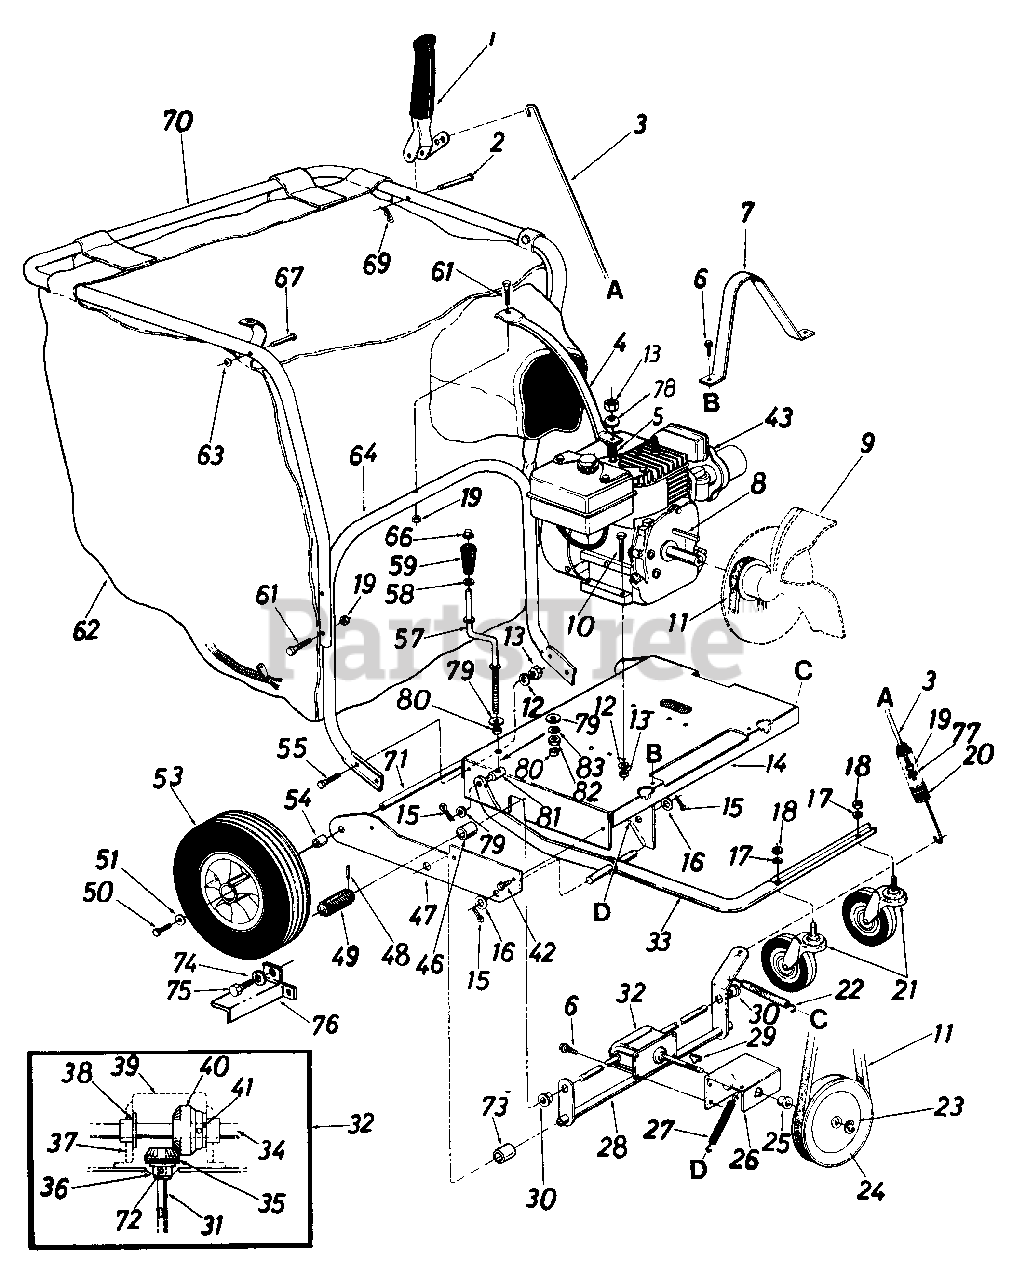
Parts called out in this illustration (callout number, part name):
1	Clutch Grip Ass'y.
2	Clevis Pin .375" Dia. x 1.88"
3	Clutch Rod 32" Lg.
4	Handle Brace
5	Part of Engine
6	Hex Wash. Hd. AB-Tap Scr. 1/4" x .62" Lg.
9	Air Vane Plate Ass'y. w/Pulley
10	Hex Bolt 5/16-18 x 1.5" Lg.
11	"V"-Belt
12	L-Wash. 5/16" I.D.
13	Hex Nut 5/16-18 Thd.
16	FI-Wash..63" I.D. x 1.25" O.D.
17	L-Wash. 1/2" I.D.
18	Hex Nut 1/2-13 Thd.
19	Hex Cent. L-Nut 1/4-20 Thd.
20	Extension Spring .78" O.D. x .75" Lg.
21	Swivel Caster Wheel 5" Dia. x 1.25"
22	Extension Spring .38" O.D. x 7.50" Lg.
23	Snap "E"-Ring .50" Dia. Shaft
24	"V"-Pulley 5/8" x 6.50" O.D.
25	Flange Bearing .502" I.D.
28	Clutch Bracket Ass'y.
29	#2 Woodruff Key 3/32" Dia. x .81" Lg.
30	Hex Flange Bearing Bronze .625" I.D.
31	Pinion Shaft .50" Dia. x 5"
32	Gear Box Ass'y. Comp.
35	Bevel Gear .50" I.D. x 14 Teeth
36	Flange Bearing .503" I.D.
37	Gear Box
38	Flange Bearing .630" I.D.
39	Gear Box Cover
40	Bevel Gear .62" I.D. x 28 Teeth
41	Spring Pin Spiral 3/16" Dia. x 1.25" Lg.
42	Hex Wash. Hd. AB-Tap Scr. 5/16" x .75" Lg.
43	Engine
46	Spacer .63" I.D. x .88" O.D. x .56" Lg.
49	Drive Pinion
50	Hex Locking Bolt 5/16-24 x .62" Lg.
51	FI-Wash..34" I.D. x .87" O.D.
53	Wheel Ass'y. Comp. 12" x 3"
54	Spacer .63" I.D. x 1.0" 0 D. x .94" Lg.
55	Hex Bolt 5/16-18 x .75" Lg.
57	Height Adjustment Crank
58	FI-Wash..385" I.0. x .62" O.D.
59	Crank Knob
61	Hex Bolt 1/4-20 x 1.75" Lg.
62	Vacuum Bag - Felt
63	Push Speed Nut .25" Dia. Stud
67	Stud Pin .250" Dia. x 1.75"
69	Internal Cotter Pin 3/8" Dia.
70	Upper Handle
71	Rear Axle
72	Spring Roll Pin 5/32" Dia. x 1.12
73	Spacer .82" I.D. x 1.0" O.D. x .305 Lg.
74	L-Wash..265" I.D.
75	Hex Self-Tap Scr. 1/4" x 3/8" Lg.
78	Belleville Washer
79	FI-Wash..35" I.D. x .87" O.D.
80	Spacer .38" I.D. x .50" 0 D. x .18" Lg.
81	Ferrule 3/8-8 x .38" Dia.
82	Hex Nut 3/8-8 Thd.
83	L-Wash. 3/8" I.D.
14530-0499	PLATE-SIDE-RH - CUB BEIGE (0499)
14530-0637	PLATE-SIDE-RH - POWDER BLACK (0637)
14530-0662	PLATE-SIDE (RH) - OYSTER GRAY (0662)
16273-0498	Double Caster Arm Assembly, Black - OLD CUB YELLOW (0498)
16273-0637	Double Caster Arm Assembly, Black - POWDER BLACK (0637)
16273-0638	Double Caster Arm Assembly, Black - MTD/TROY-BILT RED (0638)
16273-0648	Double Caster Arm Assembly, Black - TECH GRAY (0648)
16273-0662	Double Caster Arm Assembly, Black - OYSTER GRAY (0662)
16273-0674	Double Caster Arm Assembly, Black - YARDMAN YELLOW (0674)
16273-0691	Double Caster Arm Assembly, Black - BLACK JACK (0691)
16273-0709	Double Caster Arm Assembly, Black - MASTERCRAFT GREEN (0709)
16454-0638	FRAME ASSEMBLY - MTD/TROY-BILT RED (0638)
